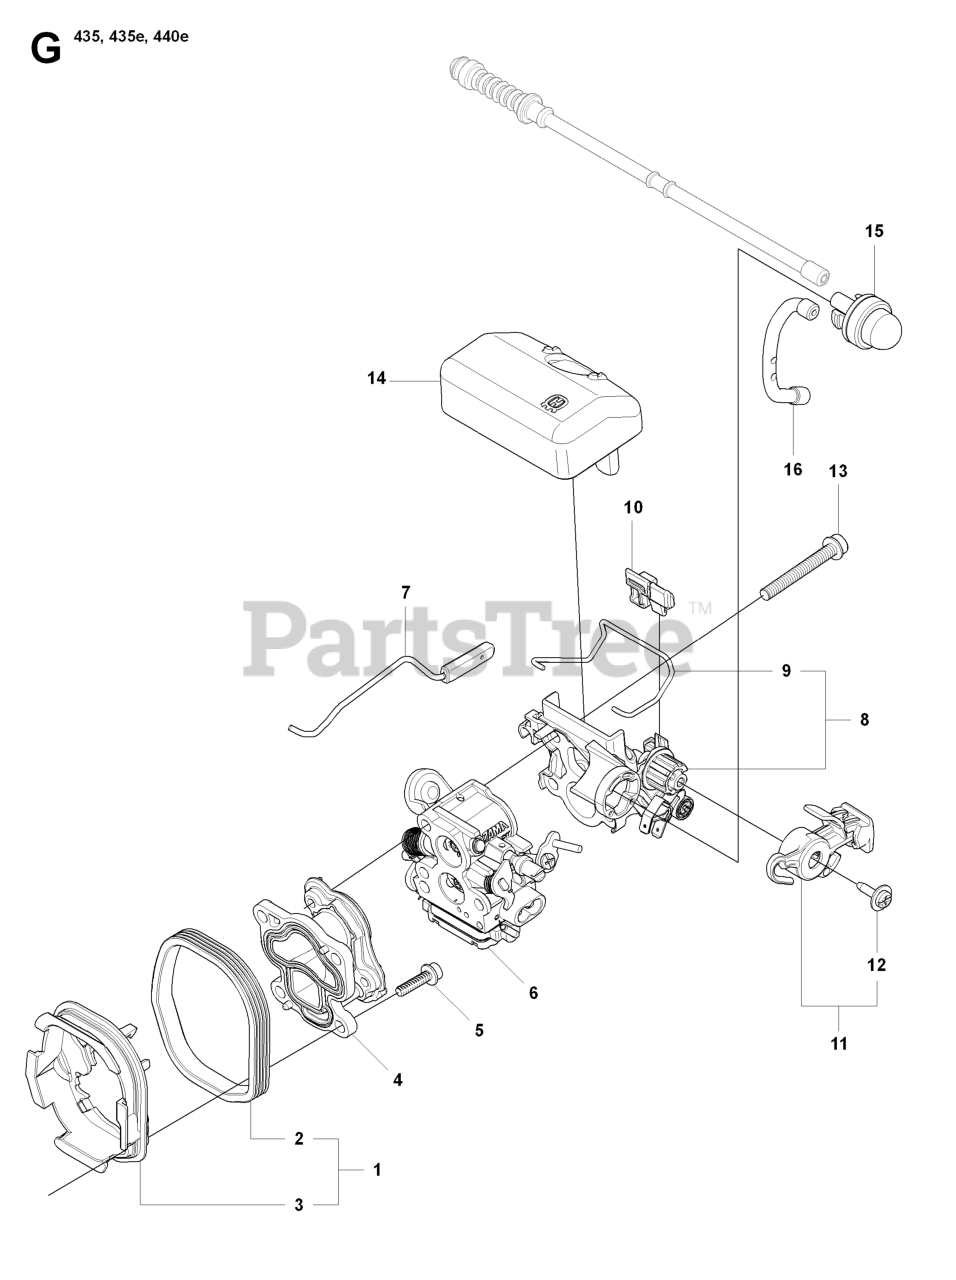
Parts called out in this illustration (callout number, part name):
1	INSULATION WALL
2	INSULATION WALL
3	INSULATION WALL
4	INLET PIPE
6	CARBURETOR
7	THROTTLE ROD ASSY
8	FILTER HOLDER
14	AIR FILTER
15	AIR PURGE BUBBLE
